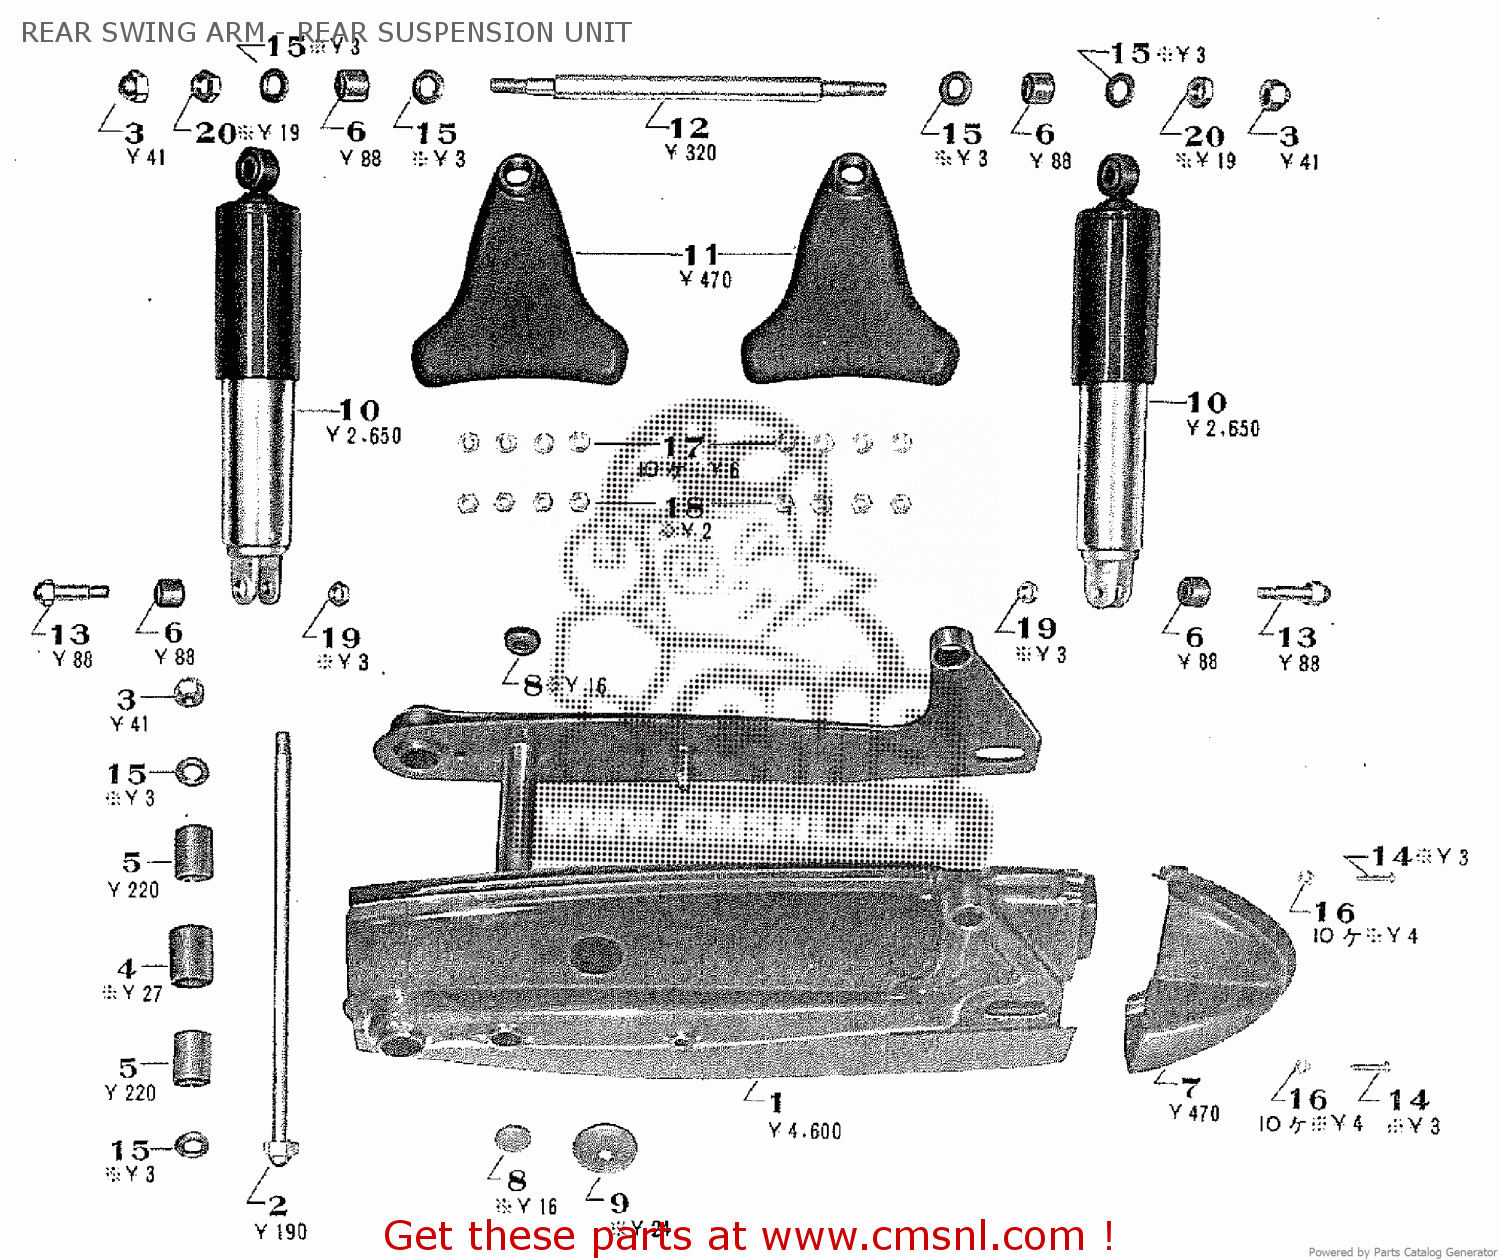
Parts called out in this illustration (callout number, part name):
1	REAR SWING ARM COMP.
2	REAR SWING ARM PIVOT SHAFT
3	PIVOT SHAFT SET NUT
4	CHAIN TOUCH DEFENCE RUBBER
5	REAR SWING ARM BUSH
6	BUSH
7	CHAIN CASE END COMP.
8	SWING ARM JOINT CAP
9	CAP
10	REAR SUSPENSION ASSY.
11	REAR SUSPENSION UPPER BRACKET COMP.
12	REAR SUSPENSION UPPER SHAFT
13	REAR SUSPENSION UNDER SET BOLT
14	6X25 CROSS SCREW
15	12MM WASHER
16	6MM SPRING WASHER
17	8MM SPRING WASHER
18	8MM HEXAGON NUT
19	10MM HEXAGON NUT
20	12MM HEXAGON NUT
